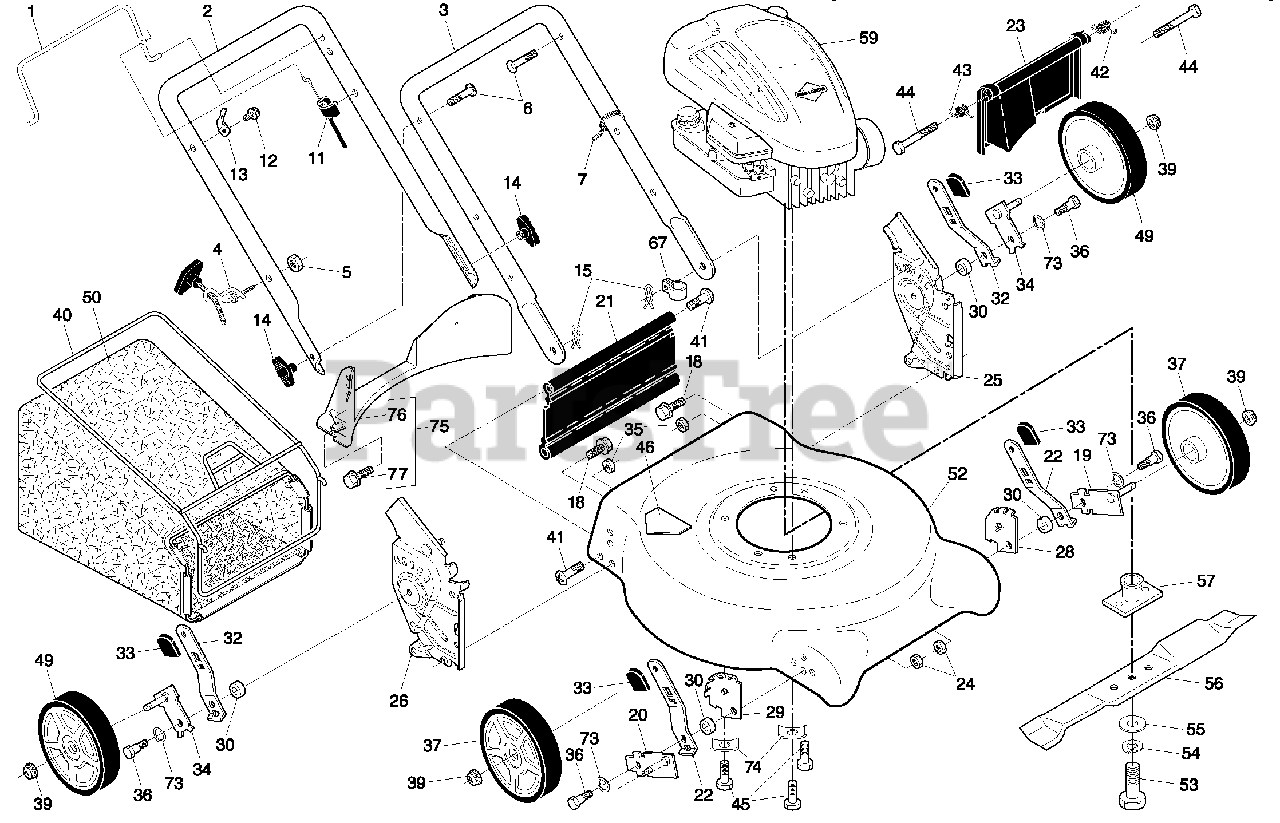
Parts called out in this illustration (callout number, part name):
1	Control Bar
2	Upper Handle
3	Lower Handle
4	Rope Guide
6	Handle Bolt
7	Wire Tie
11	Cable, Engine Zone Control
12	Hex Washer Head Screw
13	Up-Stop Bracket
14	Knob, Handle
15	Hairpin Cotter
18	Screw
19	Axle Arm Assembly, Front, LH
20	Axle Arm Assembly, Front, RH
21	Rear Skirt
22	Selector Spring, Front
23	Rear Door Assembly
24	Nut, Hex 5/16-18
25	Handle Bracket Assembly, LH
26	Handle Bracket Assembly, RH
28	Wheel Adjusting Bracket, Front, LH
29	Wheel Adjusting Bracket, Front, RH
30	Spacer
32	Selector Spring, Rear
33	Selector Knob
34	Axle Arm Assembly, Rear, LH
35	Locknut, Hex 5/16-18
36	Shoulder Bolt 5/16-18
37	Wheel & Tire Assembly, Front 7 x 1-3/4
39	Flanged Locknut, Hex
40	Frame, Grassbag
41	Hinge Screw
42	Spring, Rear Door, LH
43	Spring, Rear Door, RH
44	Bolt, Rear Door
45	Hex Head Thread Rolling Screw 3/8-16 x 1
46	Danger Decal
49	Wheel & Tire Assembly, Rear 8 x 1-3/4
50	Grassbag
52	Kit, Mower Housing
53	Hex Head Screw 3/8-24 x 1-3/8 Grade 8
54	Helical Lockwasher
55	Hardened Washer
56	21" Blade
57	Blade Adapter
67	Clip, Cable
73	Washer, Curved, Cylindrical
74	Washer, Special, Engine
75	Kit, Rear Baffle
76	Baffle, Rear
77	Screw, Rear Baffle
77	Operator's Manual, English
77	Operator's Manual, French
77	Repair Parts Manual, English / French
